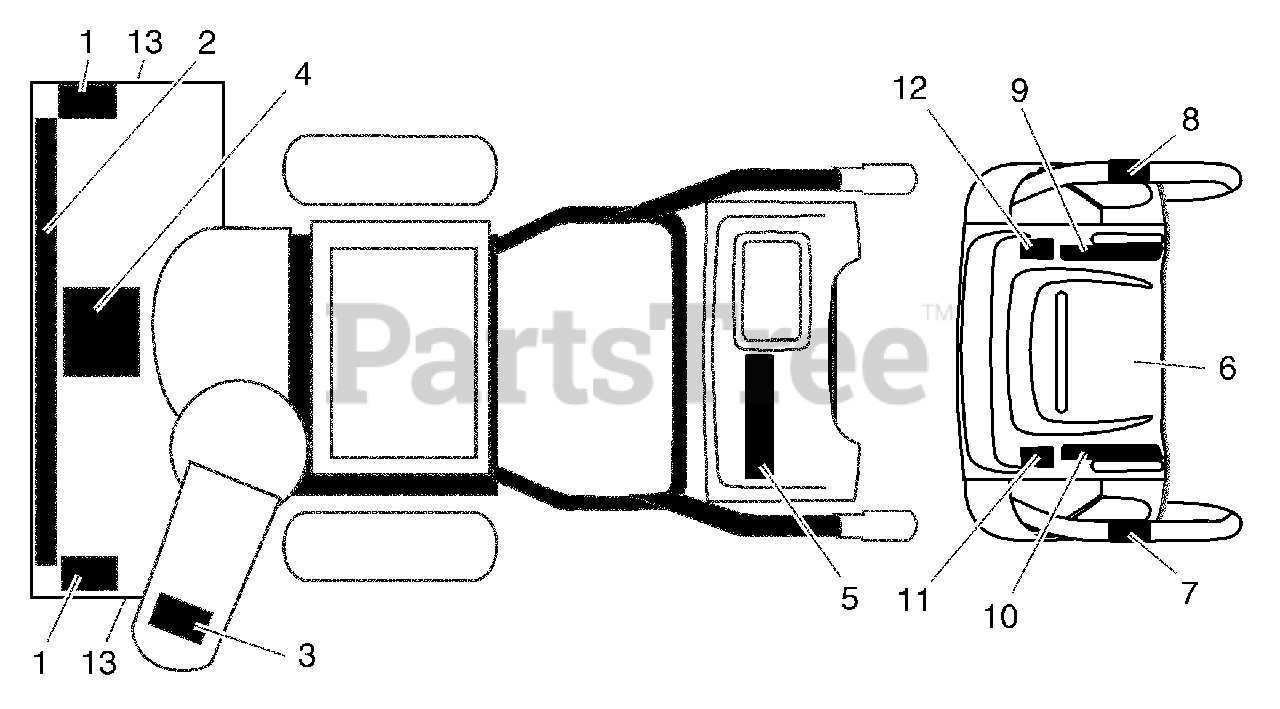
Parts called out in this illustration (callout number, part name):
1	Decal, Danger
2	Decal, Husqvarna
3	Decal, Danger, Deflector
4	Decal, Danger
5	Decal, Husqvarna, 9027ST
6	Decal, Instruction
7	Decal, Traction Lever
8	Decal, Auger Lever
9	Decal, Speed Control
10	Decal, Remote Deflector
11	Decal, LH Trigger
12	Decal, RH Trigger
13	Decal, Husqvarna, Crown
